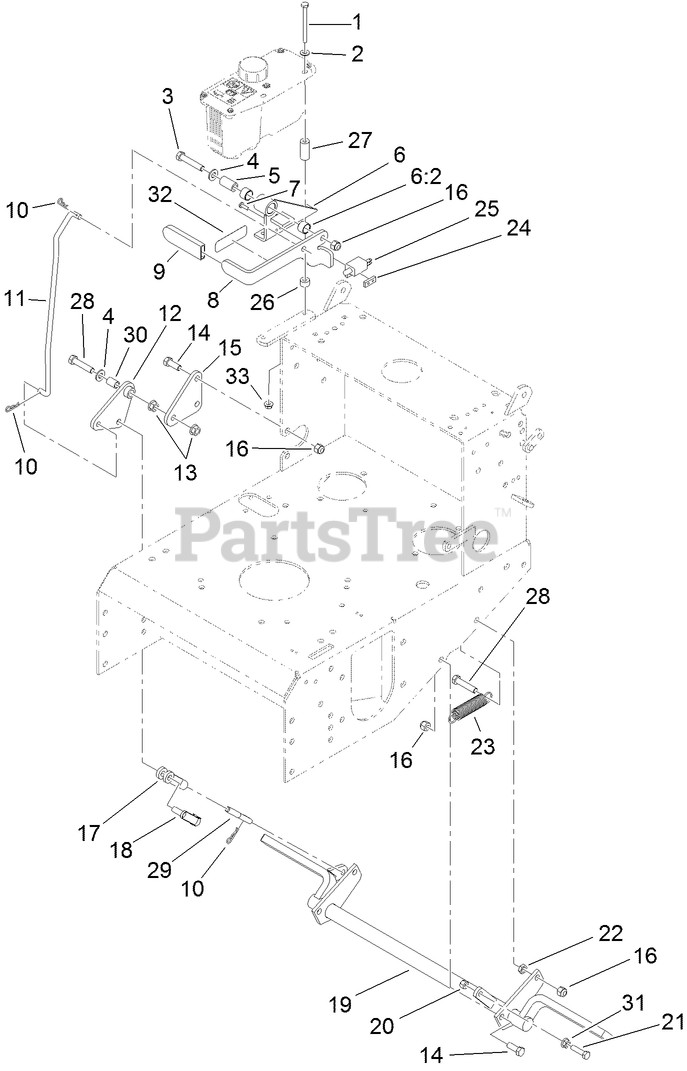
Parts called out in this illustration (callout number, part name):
1	SCREW-HH
2	WASHER-FLAT
3	SCREW-HH
4	WASHER-FLAT
5	Bushing-Pivot
6	Bracket ASM
6:2	SLEEVE-BUSHING
7	SCREW-PPH
8	LEVER-BRAKE, PARK
9	GRIP-LEVER
10	PIN-COTTER
11	Linkage-Upper
12	Bellcrank ASM
13	NUT-HF
14	SCREW-HH
15	Bellcrank
16	NUT-LOCK, NI
17	YOKE-LINKAGE, BRAKE
18	Pin-Spring, Clevis
19	BRAKE
20	NUT-LOCK, NI
21	SCREW-HH, SPECIAL
22	NUT-JAM
23	SPRING-IDLER
24	PLATE-TAPPED
25	SWITCH-OPEN, NORMALLY
26	SPACER
27	Spacer
28	SCREW-HH
29	Linkage-Lower
30	Bushing-Plastic
31	NUT-HF
32	DECAL-BRAKE, PARK
33	NUT-HF
